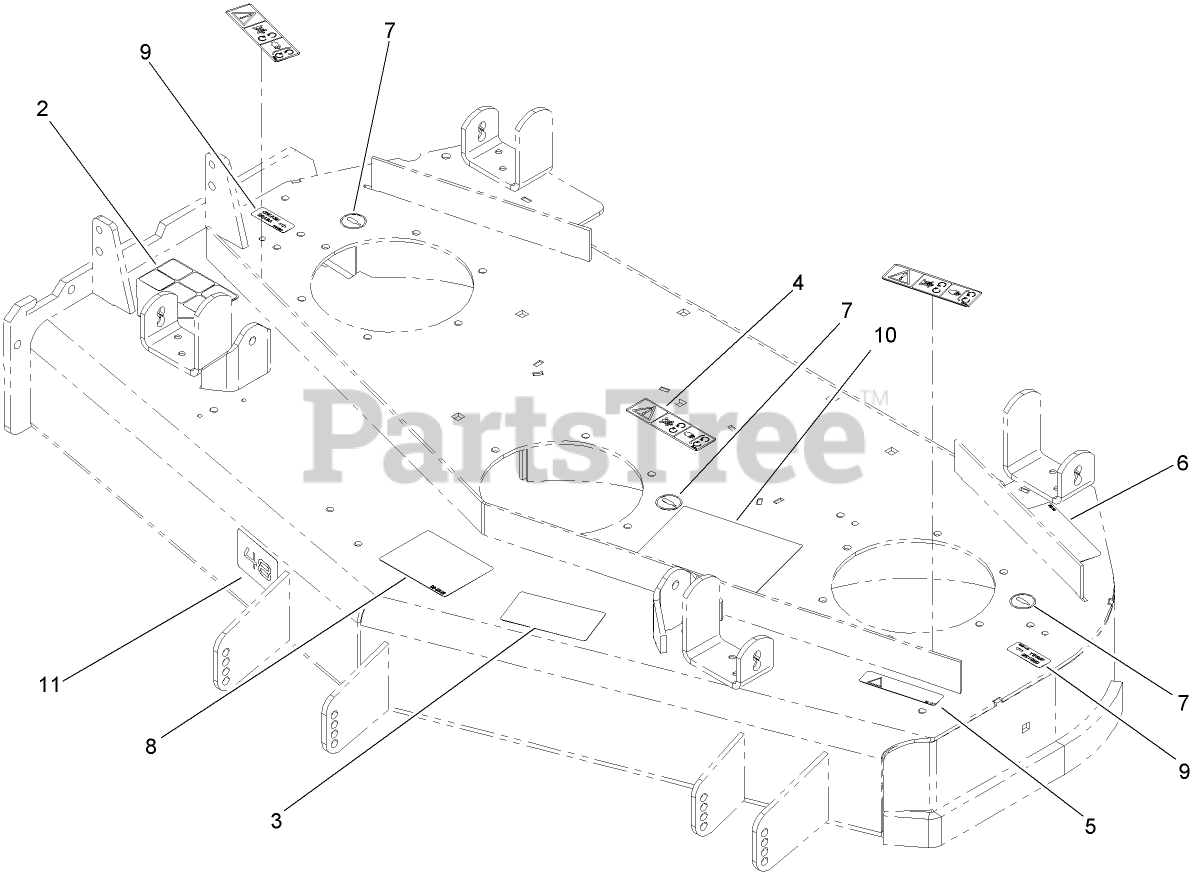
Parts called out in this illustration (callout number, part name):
2	DECAL-DANGER
3	DECAL-DANGER
4	DECAL-MISSING, COVER
5	DECAL-WARNING
6	DECAL-TORQUE, BLADE BOLT
7	DECAL-GREASE
8	DECAL-ANTI SCALP
9	Decal-Grease
10	DECAL-SERVICE AID
